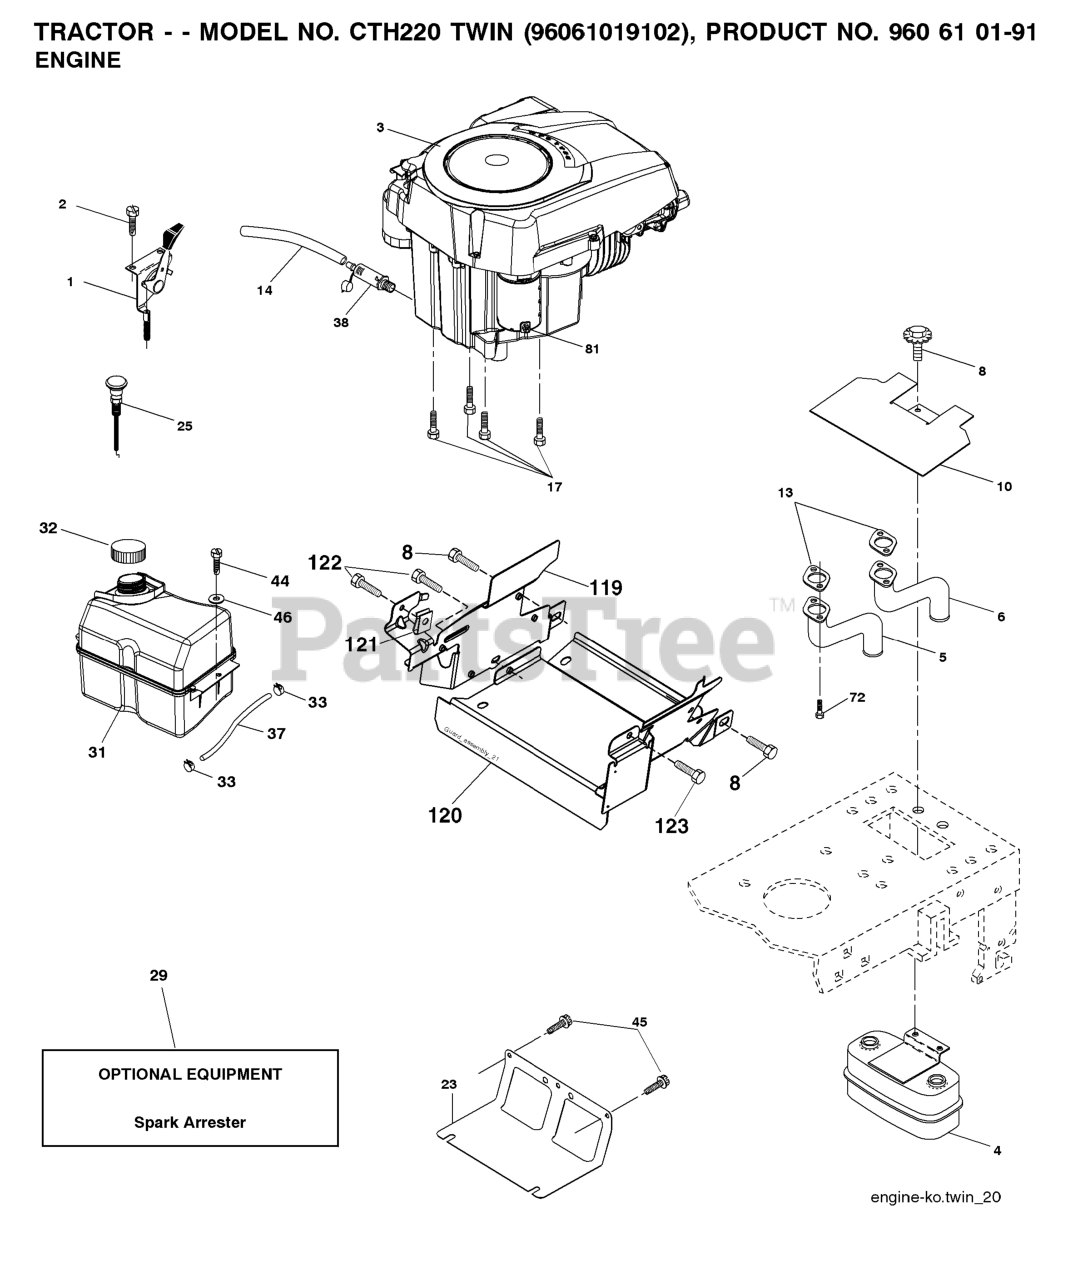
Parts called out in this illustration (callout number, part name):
1	THROTTLE CONTROL
2	SCREW
4	MUFFLER.TWIN.CYL.LOW.TONE
5	RP.PIPE-EXHAUST LH
6	RP.PIPE-EXHAUST RH
8	BOLT.5/16-18UNCX3/4 W/SEMS.BLK
10	RP SHIELD HEAT MUFFLER
14	TUBE, DRAIN OIL ASM.
17	SCREW 3/8-16X1
23	SHIELD.BROWNING.DBR.GUARD
25	CONTROL, CHOKE
29	KIT.SPARK ARRESTOR 794945 B&S
31	TANK.ASM.FUEL.FR.2.5GA.
32	FUEL CAP
33	HOSE CLAMP
37	LINE.FUEL.20
38	PLUG DRAIN OIL EASY
44	SCREW HEXWSHR 1/4-20X3/4
45	SCREW, 3/8-16X3/4
72	SCREW.SOCKET HD.5/16-1
81	NUT
119	LENKRAD
120	GUARD 532199767
122	SCREW.1/4-20X5/8
123	SCREW, 5/16-18 X 1/2
